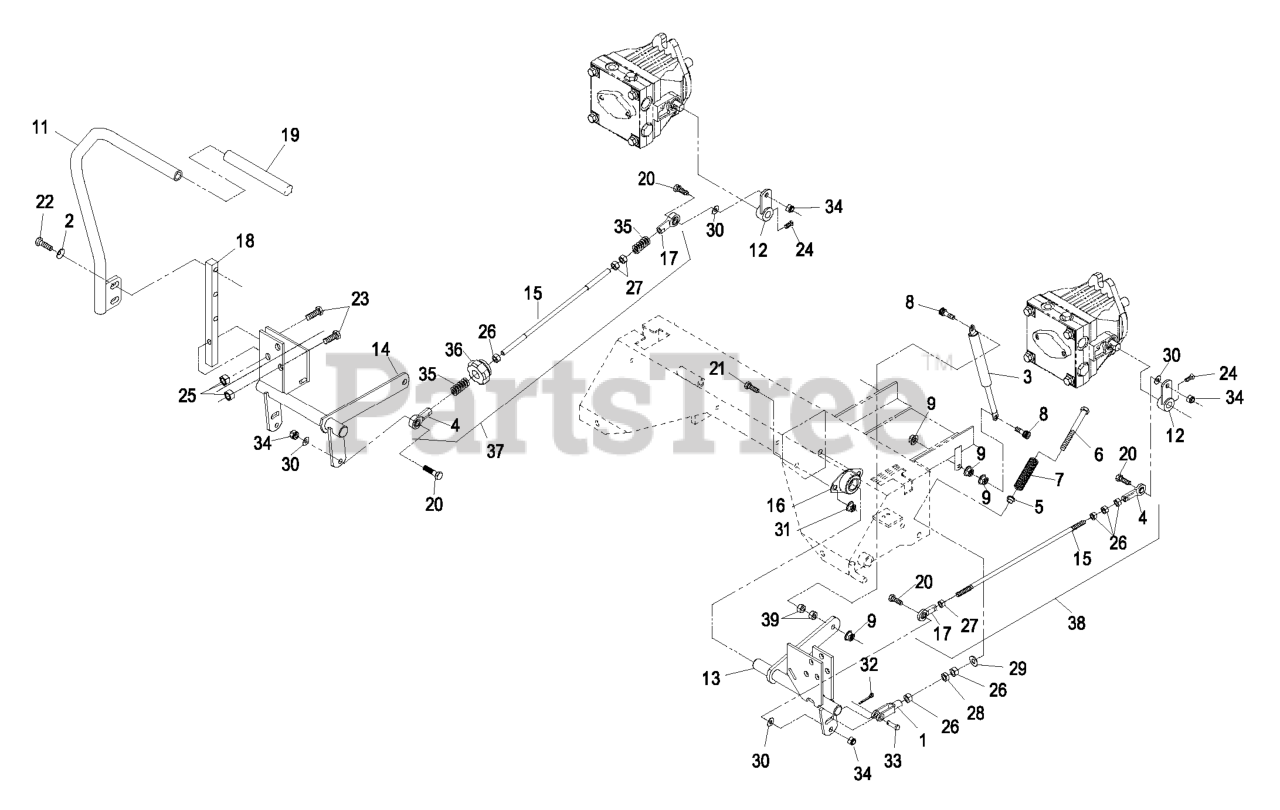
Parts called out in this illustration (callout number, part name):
1	YOKE-ADJUSTABLE
2	WASHER-BELLEVILLE
4	BALLJOINT-RH
5	BUSHING-FLANGED
6	BOLT-RETURN, NEUTRAL
7	SPRING-RETURN, NEUTRAL
8	SCREW-HH
11	ASM.RH LEVER/GRIP
12	ARM-CONTROL, PUMP
15	LINK-ROD, TRACKING
16	BEARING-FLANGE, SIDE
17	BALLJOINT-LH
18	ARM-SHAFT, CONTROL
19	GRIP,CONTROL LEVER
20	SCREW-HH
21	SCREW-HH
22	SCREW-HH
23	SCREW-HH
24	SCREW-SET
25	NUT-LOCK, NI
26	NUT-HEX
28	NUT-JAM
29	WASHER-FLAT
30	WASHER-FLAT
31	NUT-HHF, WHIZ
32	PIN-COTTER
33	PIN-CLEVIS
34	NUT-LOCK, NI
35	SPRING-COMPRESSION
36	KNOB-TRACKING
37	TRACKING ROD ASM
38	TRACKING ROD ASM
39	NUT-HEX
